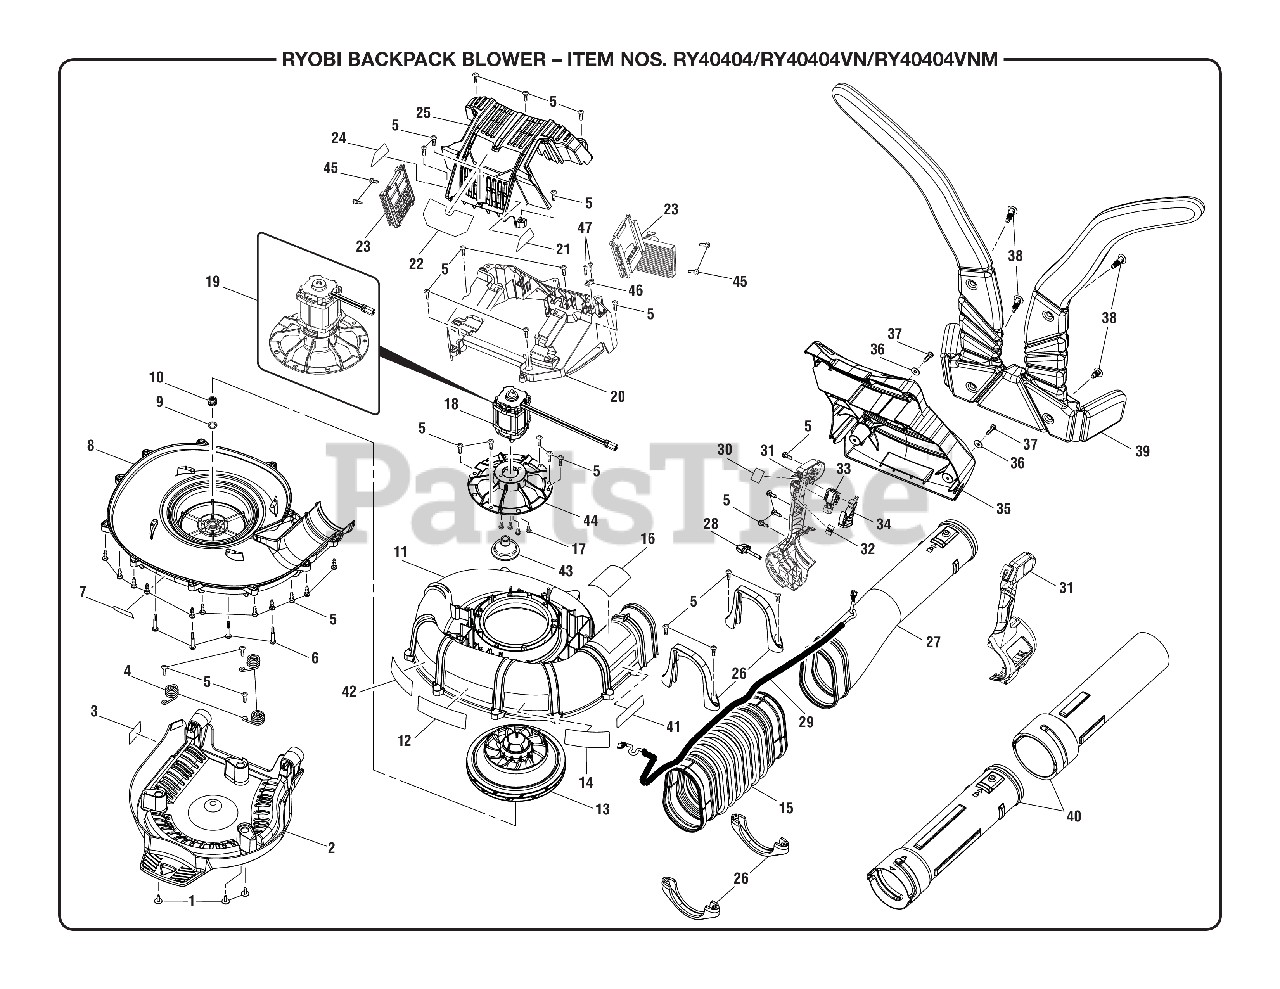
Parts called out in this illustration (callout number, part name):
1	Screw (10-14 x 16 mm)
2	Lower Frame Assembly
3	Data Label
5	Screw (10-14 x 19 mm, T25 Torx Truss Pan Hd. T.F.)
6	Shoulder Screw (M5 x 40 mm, T25 Torx Truss Hd. T.F.)
7	Hair Ingestion Warning Label
8	Outer Volute Assembly
9	Washer (OD18 x ID12.15 x 1.5t)
10	Wavy Spring (ID6.51 x HGT9.52)
11	Inner Volute Assembly
12	Ryobi Logo Label
13	Fan Assembly
14	MPH Label
15	Bellows Tube
16	Warning Icon Label
17	Screw w/Lock Washer (M5 x 8 mm, Pan Hd.)
18	Motor (40 volt)
19	Motor & Mount Assembly
20	Housing Cover (Bottom)
21	Warning Label (French)
22	40V Lithium Label
23	Motor Controller & Battery
24	Warning Label (Spanish)
25	Housing Cover Assembly
26	Clamp Assembly
27	Handle Blower Tube
28	Adjustment Knob (1/4-20 UNC)
29	Wire Assembly
30	Turbo Label
31	Throttle Handle & Cruise Control Assembly
32	Turbo Switch
33	Switch Assembly
35	Upper Frame
36	Washer (OD16 x ID6.8 x 1.5t)
37	SCREW (10-14 X 1 in.)
38	Harness Snap Fastener
40	Blower Tube Assembly
41	Battery Warning Label
42	CFM Label
43	Drive Coupler
44	Motor Mount
45	Screw, M4-18 x 12mm, T20 Torx Pan Head
46	Cord Clamp
47	Screw (M4 x 14 mm, T15 Torx Pan Hd.))
